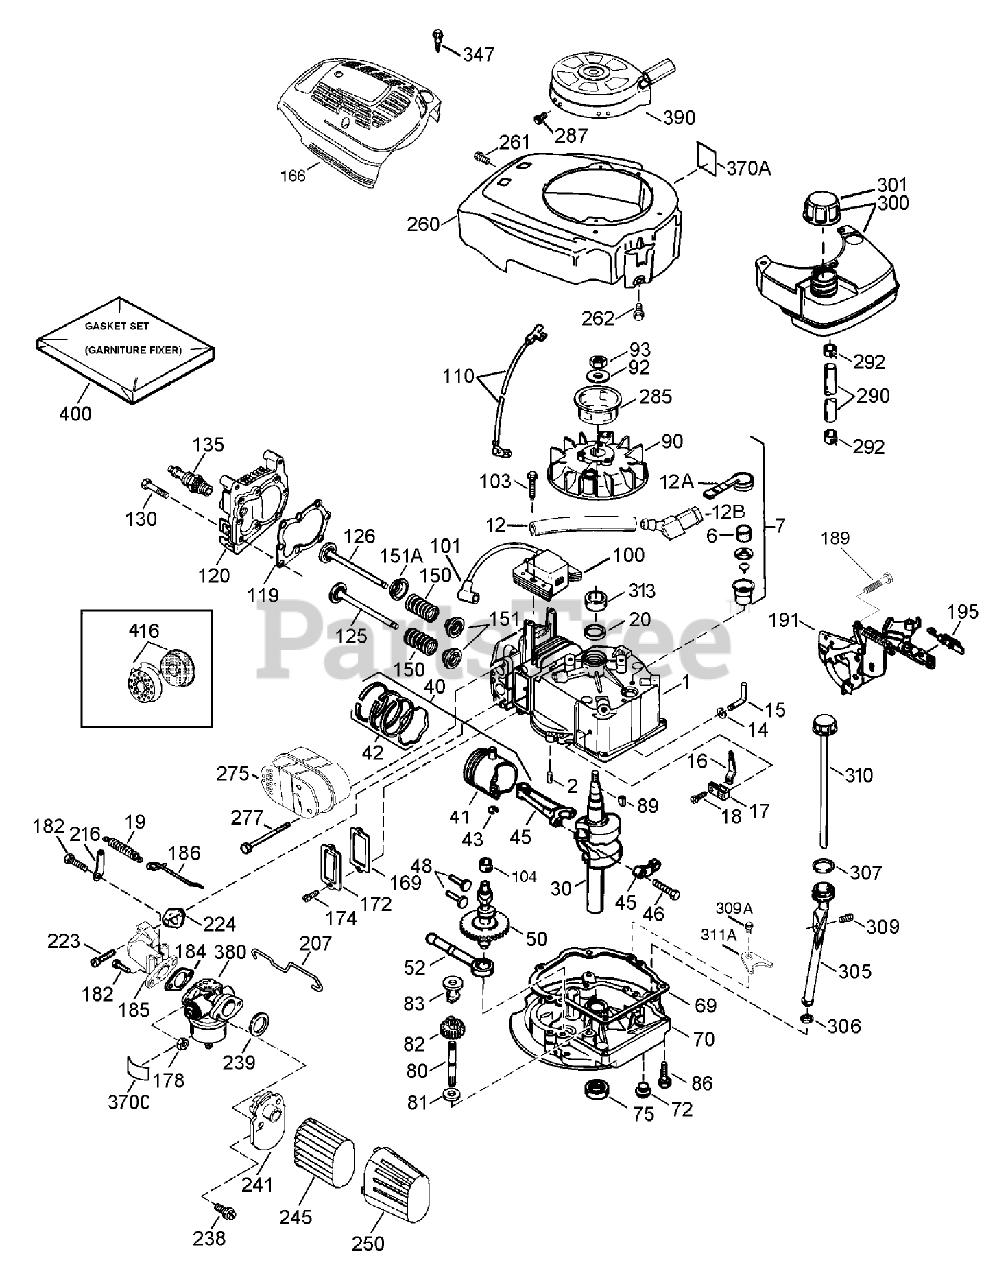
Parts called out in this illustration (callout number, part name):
1	Cylinder ASM
2	Pin-Dowel
6	Element-Breather
7	Breather ASM (Incl. Ref. #6 and 12A)
12	Tube-Breather
12A	Breather Cover and Tube (Incl. Ref. #12B)
12B	Elbow-Tube, Breather
14	Washer-Flat
15	Rod, Governor (Incl. No. 36)
16	Lever-Governor
17	Clamp-Lever, Governor
18	Screw (T-15, 8-32 x 19/64)
19	Spring-Extension
20	Seal-Oil
30	Crankshaft
40	Piston, Pin and Ring Set (Std.)
41	Piston and Pin ASM (Std.) (Incl. Ref. # 43)
42	FITTING - TANK 3/4"
43	Ring-Retaining, Piston Pin
45	Connecting Rod ASM (Incl. Ref. #46)
46	Bolt-Rod, Connecting
48	Lifter-Valve
50	Camshaft (Exhaust MCR) (Incl. Ref. #104)
52	Oil Pump ASM
69	Gasket-Flange, Mounting
70	Flange-Mounting (Incl. Ref. #72-83,306,309A 311A)
72	Plug-Drain, Oil
75	Seal-Oil
80	Shaft-Governor
81	Washer-Flat
82	Governor Gear ASM
83	Spool-Governor
86	Screw (1/4-20 x 1-1/4)
89	Key-Flywheel
90	Flywheel
92	Washer-Belleville
93	Nut-Flywheel
100	Ignition-State, Solid
101	Cover-Spark Plug
103	Screw (T-15, 10-24 x 15/16)
104	Bushing-Cam
110	Wire-Ground
119	Gasket-Cylinder Head
120	Head-Cylinder
125	Valve-Exhaust (1/32in OS) (Incl. 151)
125	Valve-Exhaust (Std.) (Incl. Ref. #151)
126	Valve-Intake (Std.) (Incl. Ref. #151 and 151A)
130	Screw (5/16-18x1-1/2)
135	Spark Plug-Resistor (R J19 L M)
150	Spring-Valve
151	Cap-Valve, Spring
151A	BEARING - TRANS
166	Shroud-Engine
169	Gasket-Cover, Valve
172	Cover-Valve
174	Screw (10-24 x 9/16)
178	Nut and Lock Washer (1/4-28)
184	Gasket
185	Pipe-Intake
186	Link-Governor
189	Screw (1/4-20 x 3/8)
191	Bracket-S.E. Brake (Incl. Ref. #195)
195	Terminal
207	Link-Throttle
216	Lever-Adjusting, R P M
223	Screw (1/4-20 x 1)
224	Gasket-Pipe, Intake
238	Screw (10-32 x 49/64)
239	Gasket-Cleaner, Air
241	Collar-Cleaner, Air
245	Filter-Cleaner, Air (Paper)
250	Cover-Cleaner, Air
260	Housing-Blower
261	Screw (10-24 x 9/16)
262	Screw (1/4-20 x 1/2)
275	Muffler
277	Screw (1/4-20 x 2-9/32)
285	Cup-Starter
287	Screw (8-32 x 21/64)
290	Line-Fuel (8.62)
292	Clamp-Line, Fuel
300	Fuel Tank (Incl. Ref. #292 and 301)
